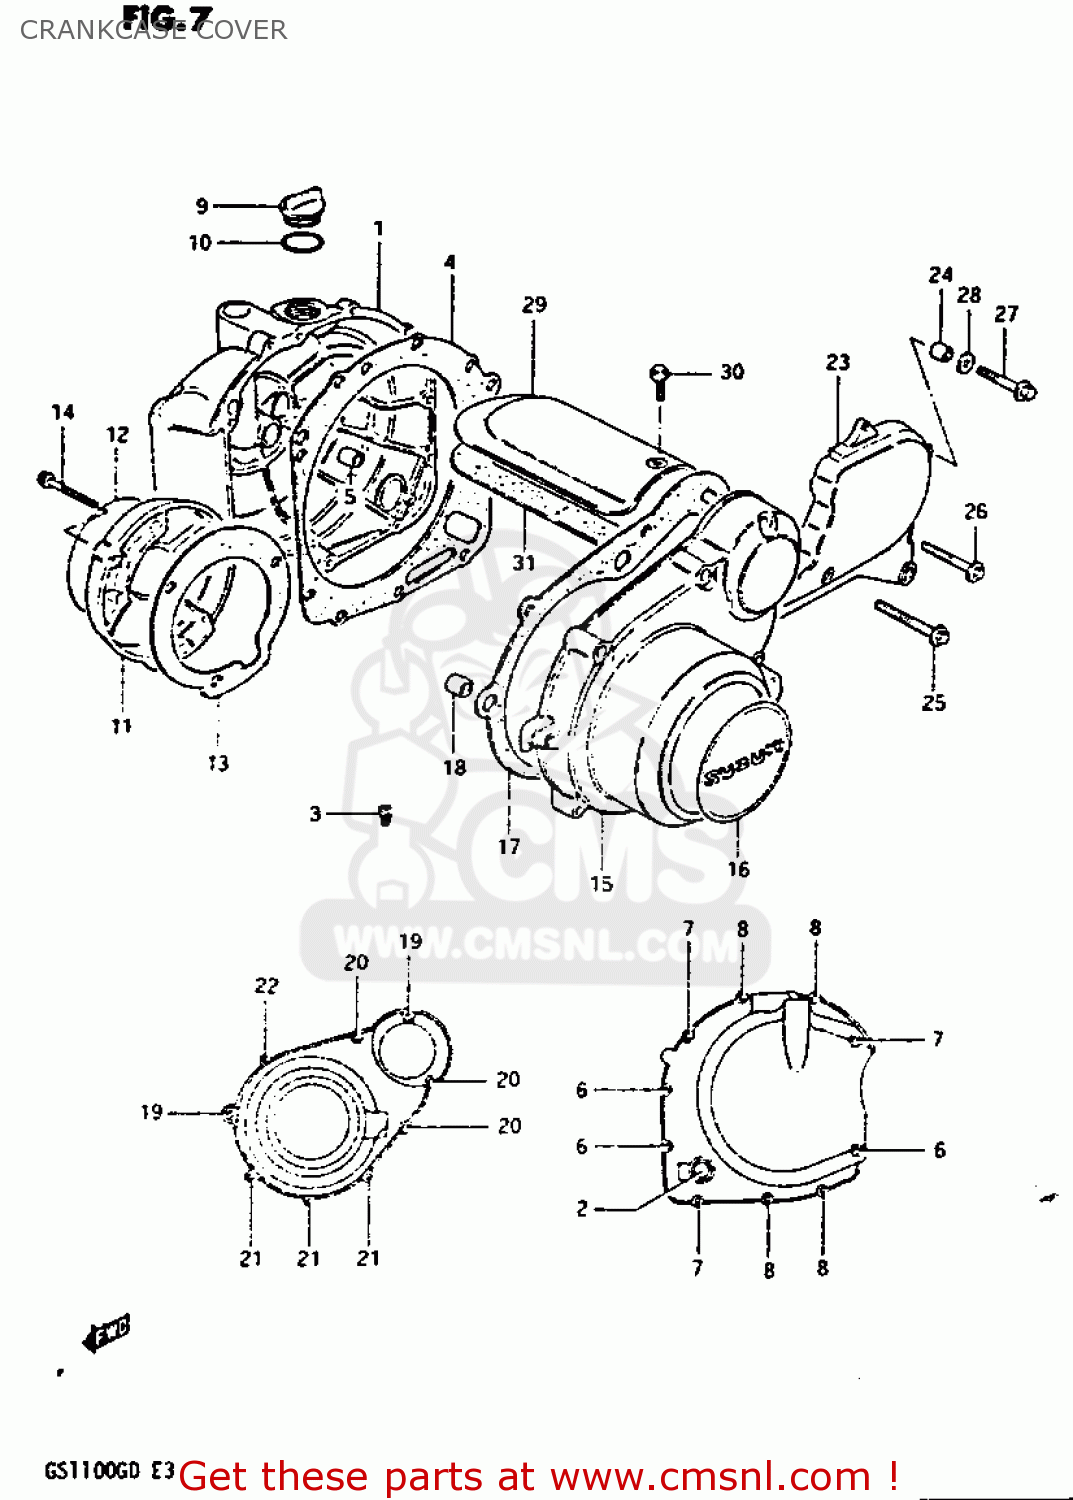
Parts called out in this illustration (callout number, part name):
1	COVER,CLUTCH
2	LENS,OIL LEVEL CHECK
3	JET
4	GASKET,MAGNETO COVER (NAS)
5	PIN
6	BOLT
7	BOLT
8	BOLT
9	PLUG SET
10	O RING(D:2.2,ID:32)
11	COVER,CONTACT BREAKER
12	EMBLEM,CONTACT BREAKER COVER
13	GASKET,CONTACT BREAKER COVER (NAS)
14	BOLT
15	COVER,MAGNETO
16	EMBLEM,MAGNETO COVER
17	GASKET,MAGNETO COVER (NAS)
18	PIN
19	BOLT
20	BOLT
21	BOLT
22	BOLT
23	COVER,SECONDARY DRIVE
24	PIN
25	BOLT
26	BOLT
27	BOLT
28	WASHER
29	COVER,STARTER MOTOR
30	BOLT
31	GASKET,STARTING MOTOR COVER (NAS)
